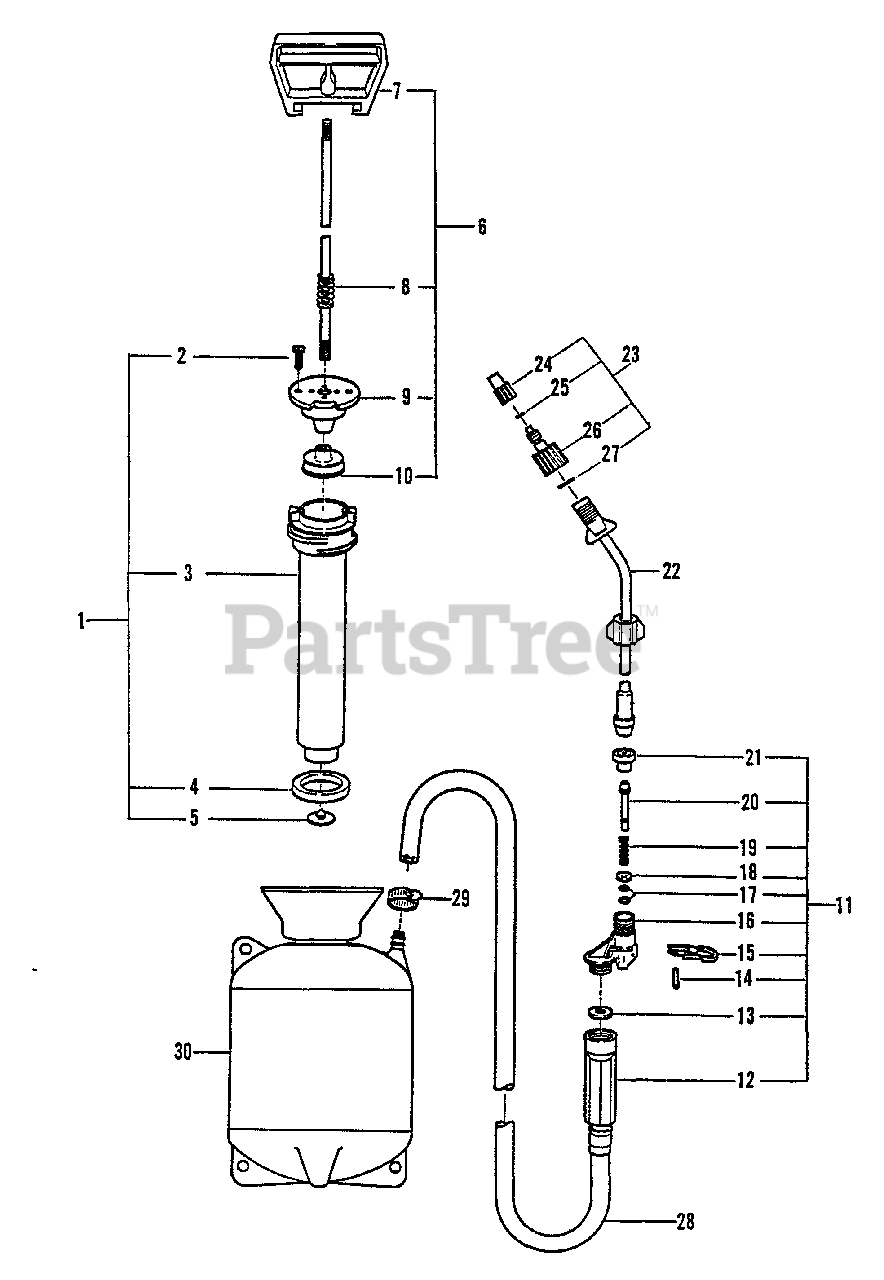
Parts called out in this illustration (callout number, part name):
1	PUMP ASSY
2	SCREW
3	CYLINDER, PUMP
4	GASKET, PUMP
5	VALVE, CHECK
6	PUMP ASSY
7	HANDLE, PUMP
8	SPRING
9	COVER, CYLINDER
10	PISTON ASSY
11	SHUT-OFF VALVE ASSY
12	HANDLE
13	WASHER
14	PIN
15	TRIGGER
16	VALVE
17	O-RING
18	WASHER
19	SPRING
21	SEAT, VALVE
22	EXTENSION, 16" STD (BRASS)
23	NOZZLE (PLASTIC) STD
25	O-RING
26	BODY
27	O-RING
28	HOSE - 39"
29	CLAMP, HOSE
30	TANK
